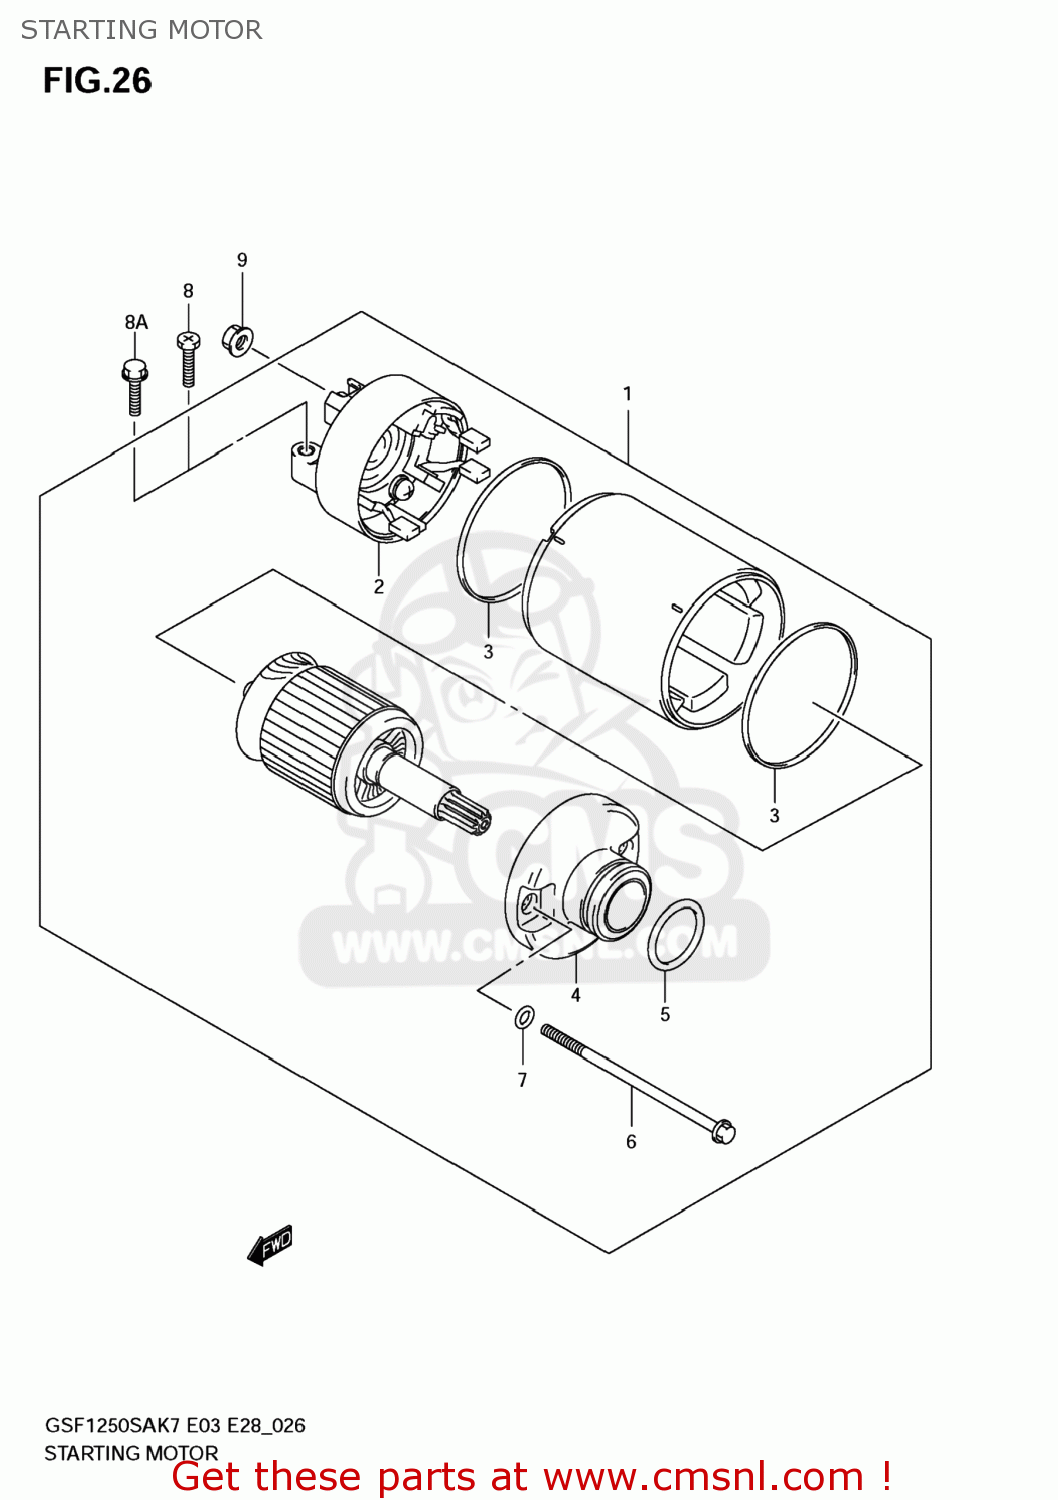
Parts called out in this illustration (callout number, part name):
1	MOTOR ASSY,STARTING
2	FRAME ASSY
3	O RING
4	HOUSING ASSY
5	O RING(D:3,ID:24.5)
6	BOLT
7	O RING
8	SCREW (6X25)
8A	BOLT(6X25)
9	NUT
